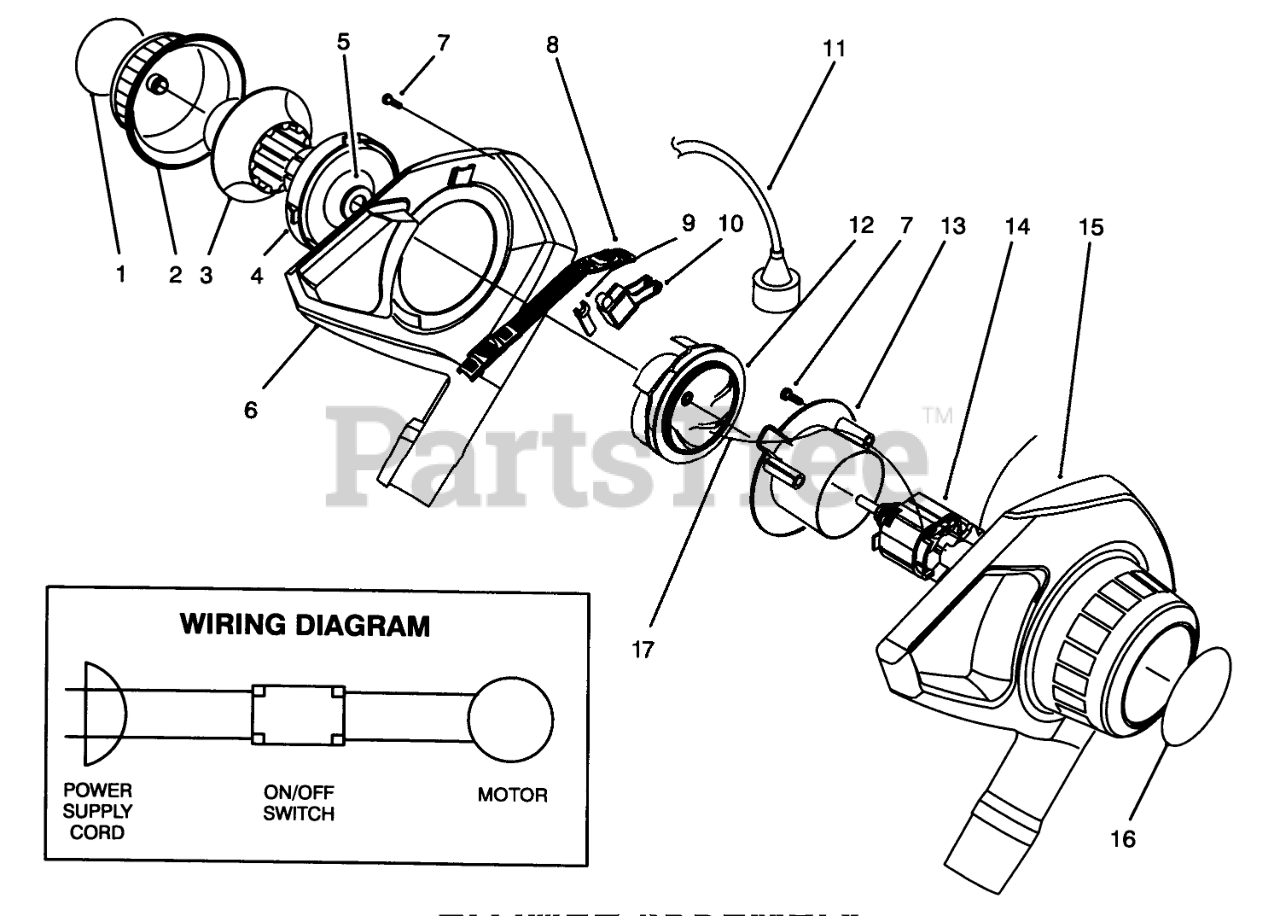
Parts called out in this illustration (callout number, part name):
1	DECAL, 700 CHOKE
2	CHOKE COVER, 600/700
3	MID BL-RING CHOKE
4	MID-BLOWER BASE CHOKE
5	RETAINER CLIP
6	HOUSING ASSY, RH
7	Screw
8	SWITCH BAR, 600/700
9	MID BL-ACTUATOR
10	SWITCH
11	POWER SUPPLY CORD
12	Impeller Assembly
13	RETAINING PLATE
14	MOTOR, MID-RANGE BLOWER
15	HOUSING, LH
16	SERIAL DECAL 700
